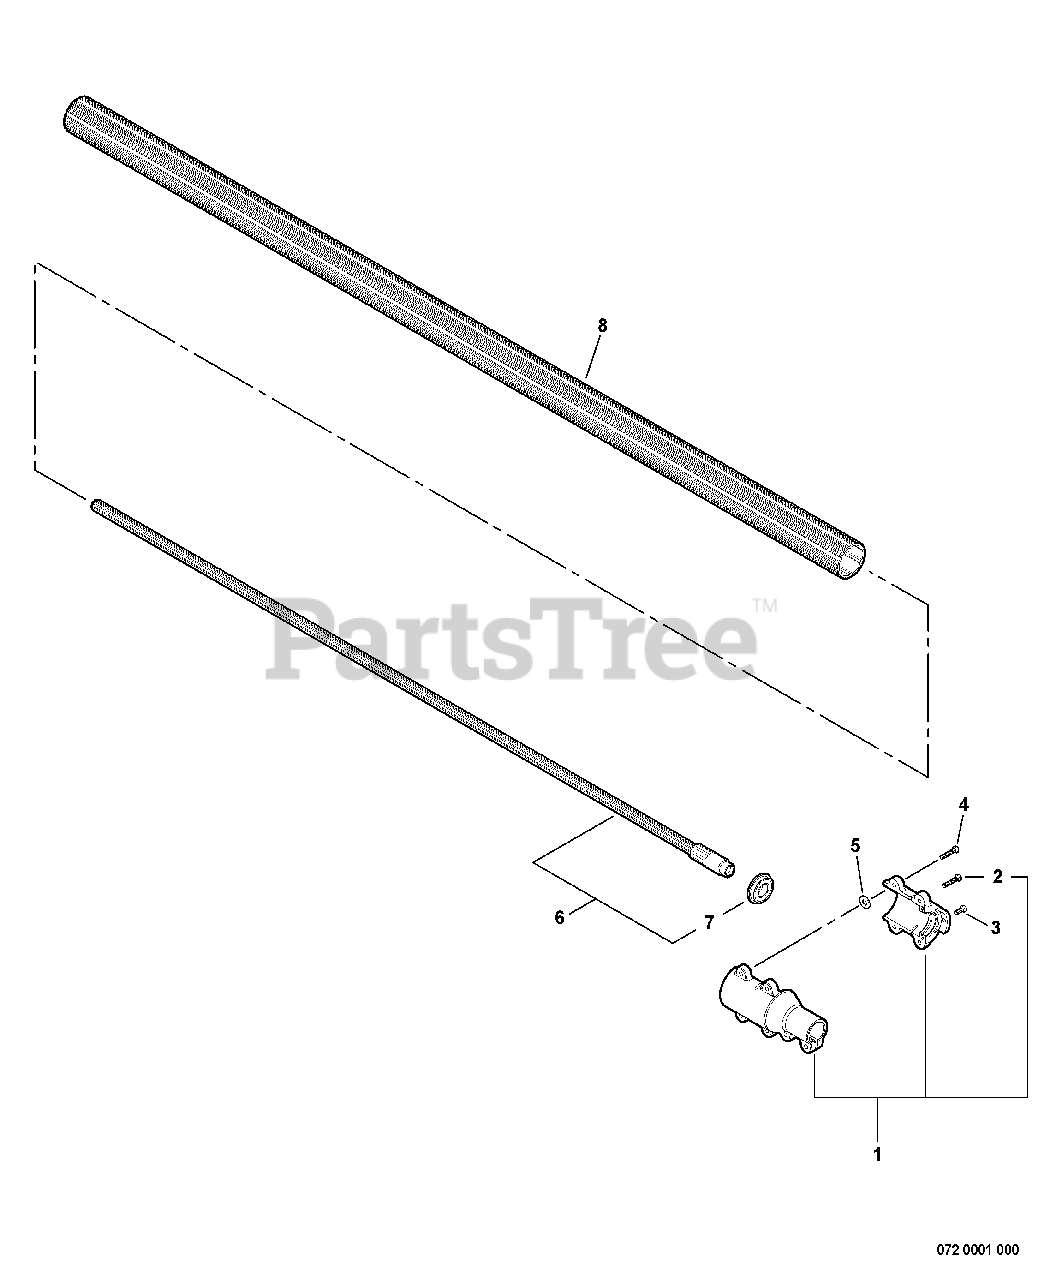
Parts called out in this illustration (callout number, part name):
1	COUPLING ASSY
2	SCREW - 5X20
3	SCREW - 5X10
4	SCREW - 5X20
5	WASHER - 5
6	DRIVESHAFT ASSY - LOWER
7	BEARING, BALL - 6002
8	PIPE, MAIN - ORANGE
